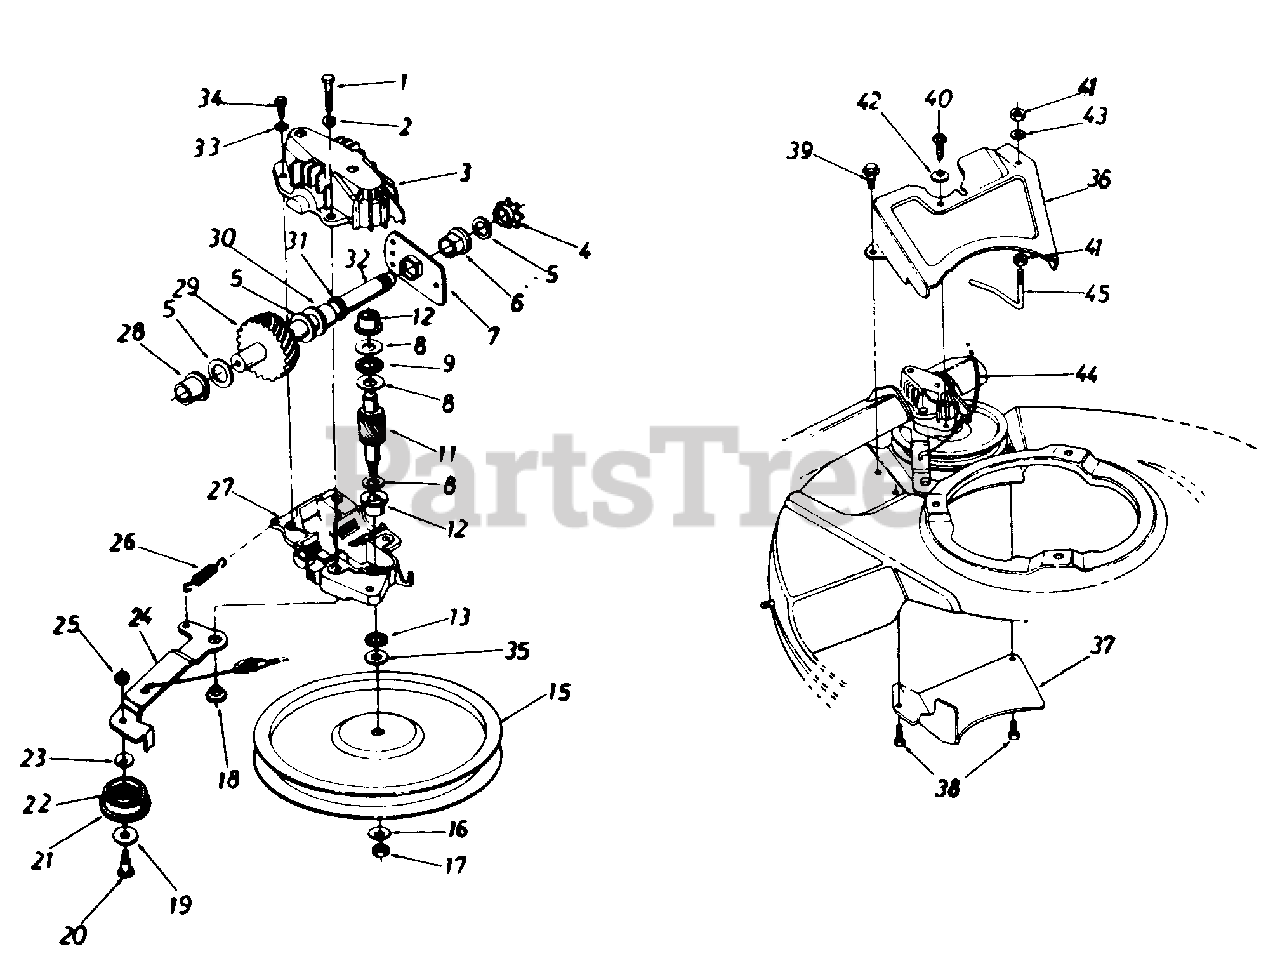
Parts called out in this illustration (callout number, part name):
1	Hex Bolt 1/4-20 x 1.25" Lg. w/Patch
2	L-Wash. 1/4" I.D.
3	Upper Hsg. Half
4	#48 Sprocket 7 Tooth x 1/2 Pitch
5	FL-Wash. 5/8" I.D. x .030
6	Hex Flange Brg. .631" I.D.
8	Thrust Wash. .382" I.D. x .70" O.D.
9	Thrust Bearing .375" I.D. x .812" O.D.
11	11 Tooth Helical Gear
12	Flange Bearing
13	Oil Seal
15	FL-Pulley 5.06" I.D.
16	Bell-Wash. .265" I.D. x .75"
17	Hex Nut 1/4-28 L.H. Thd.
18	Shld. Spacer .375" Dia. x .170
19	FL-Wash. .390" I.D. x 1.0"
20	Shld. Bolt. 375" Dia. x .40"
21	FL-Idler Plastic 1.50" Dia.
22	Needle Brg. .375" x .31"
23	Bell-Wash. .265" I.D. x .75"
24	Idler Brk't. Ass'y.
25	Hex Patch L-Nut 1/4-28 Thd.
26	Extension Spring 1.12" Lg.
27	Lower Hsg. Half
28	Flange Bearing .56 Dia.
29	33 Tooth Helical Gear
30	Flange Bearing .629 Dia.
31	Oil Seal .625 Dia.
32	Gear Sprocket Shaft
33	L-Wash. #10 I.D.
34	Hex B-Tap Scr. #10 x .62"
35	Hex Washer .26" x .88"
39	Hex AB-Tap Scr. 1/4 x .50" Lg.
40	Hex B-Tap Scr. 1/4 x .62" Lg.
41	Hex Nut 1/4-20 Thd.
42	Bell-Wash. 2.65" I.D. x .75"
43	L-Wash. 1/4" I.D.
44	S.P. Cable--48" Lg.
45	S.P. Belt Guard
